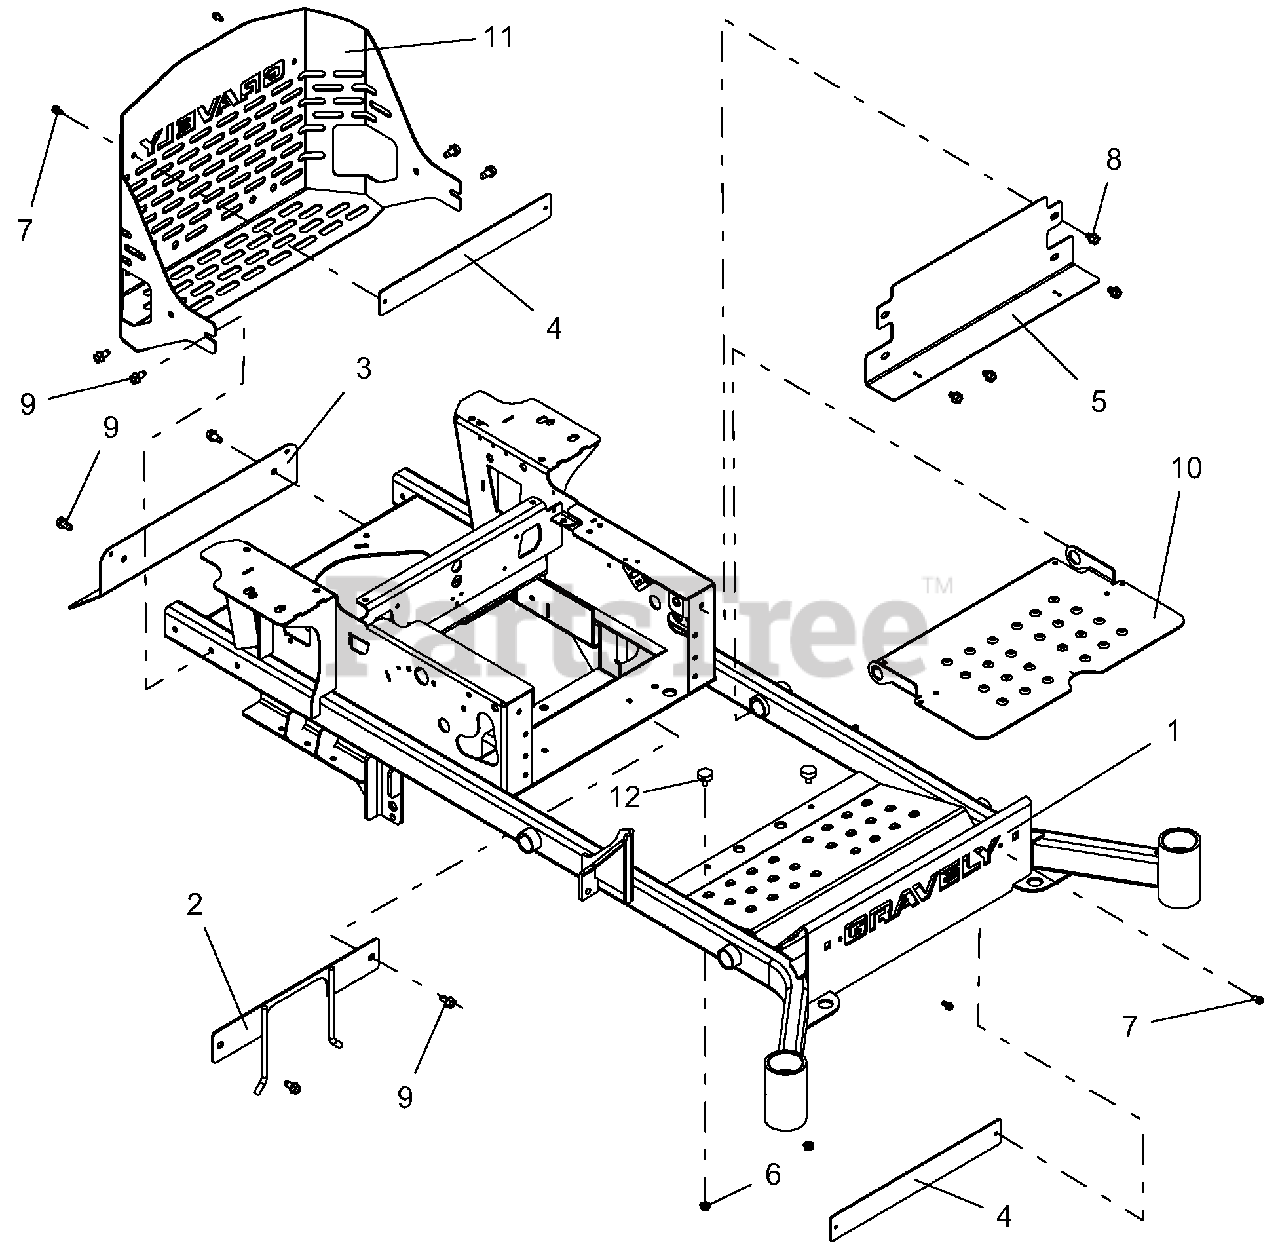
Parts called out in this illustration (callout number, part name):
1	60" MAIN FRAME W/SAFETY DECALS
2	WLDMT, PTO BELT FINGER-BLACK
3	SHIELD, MUFFLER HEAT-BLACK
4	PLATE, BUMPER 2.00 x 16.50 - BLK
5	PLATE, PT/PT100 KICK-RED
6	@NUT-SPNLK-FLG .312-18 YWZC
7	SCR-TAP .25-20X.50 HWH TR YWZ
8	SCR-TAP .38-16X.50 HWH TR YWZ
9	SCR-TAP .38-16X.75 HWH TR YWZ
10	FOOT, PLATE W/SAFETY DECALS
11	REAR BUMPER W/SAFETY DECALS
12	BUMPER, RUBBER
